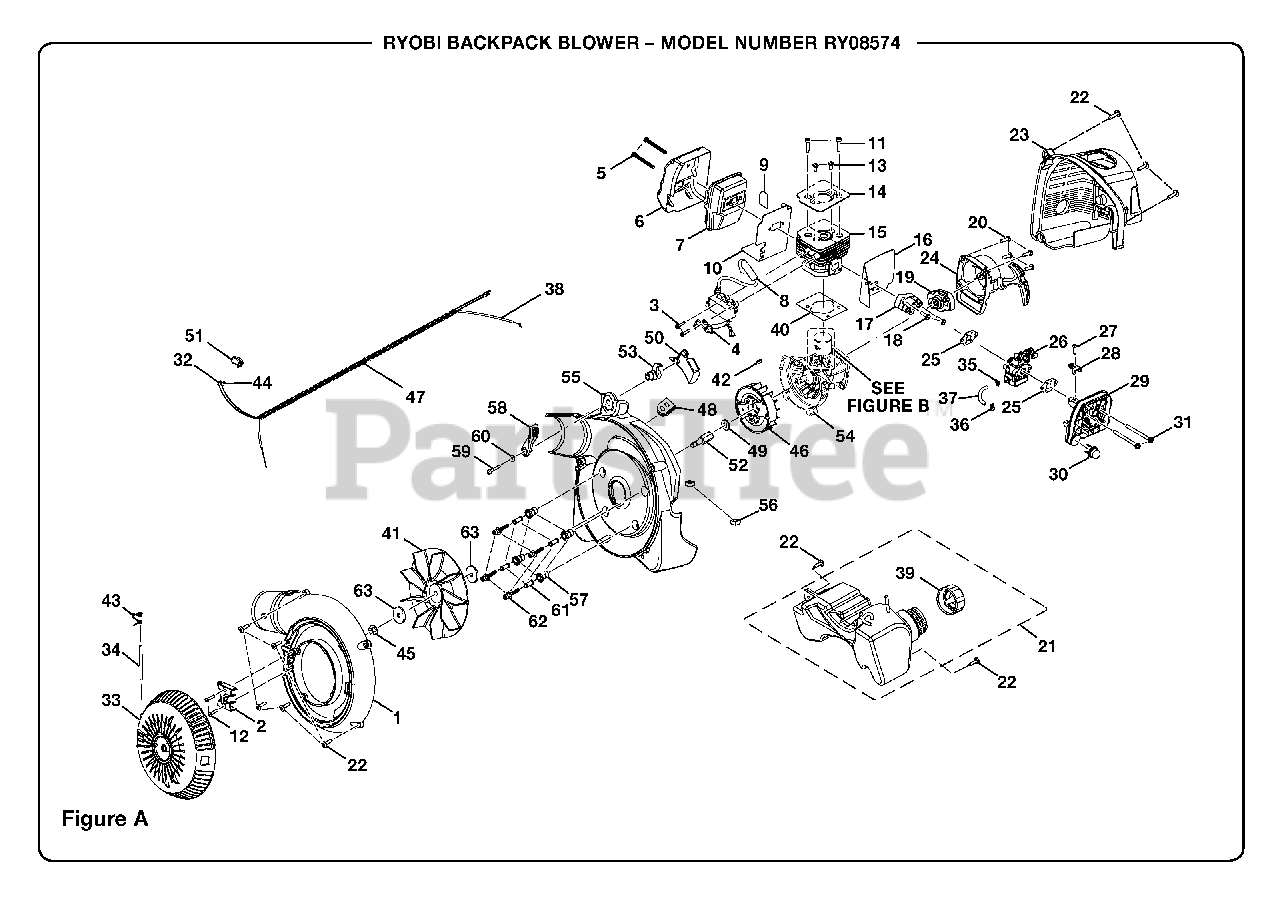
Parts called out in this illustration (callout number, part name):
1	Outer Volute Housing
2	Vacuum Door Hinge
3	Screw (M4 X 22 mm)
4	Lead Assembly
5	Screw (M5 X 50 mm)
6	Heat Shield
7	Muffler Assembly
8	Coil & Boot Assembly
9	Heat Shield
10	Gasket Muffler
11	Screw (M5 X 22 mm)
12	Screw (#8-14 X 163 mm)
13	Screw & Washer (M5 X 10 mm)
14	Plate for Cylinder
15	Cylinder
16	Insulator Gasket
17	Insulator
18	Screw & Washer (M5 X 31 mm)
19	Pulley Assembly
20	Screw (M5 X 16 mm)
21	Fuel Tank Assembly
22	Screw (#10-14 X 7/8 in)
23	Engine Shroud Housing
24	Starter Assembly
25	Carburetor Gasket
26	Carburetor
27	Screw (M4 X 175 X16 mm Pan Hd)
28	Clip-throttle Cable
29	Air Box Base
30	Primer Assembly
31	Screw (M5 X 60 mm)
32	Lead Assembly (Red)
33	Vacuum Door
34	Hinge Pin
35	Clip-hose (Id 4.9)
36	Clip-hose
37	Tubing Rubber
38	Cable Assembly
39	Fuel Cap Assembly
40	Cylinder Gasket
41	24.5 Cc Blower Fan
42	Key Woodruff (S43C)
43	Vacuum Door Hinge Spring
44	Lead Assembly (Black)
45	Retaining Washer Nut
46	Fly-wheel Assembly
47	Corrugated Tube
48	Rubber Grommet
49	Washer (2 mm)
52	Crank Shaft Extension
53	Trigger Lock
54	Crankcase Assembly
55	Housing Inner Volute
56	Square Nut
57	Vibration Isolator
58	Cruise Lever
59	Screw (#8-14 X 25 mm)
61	Bushing Sleeve
62	Screw (M5 X 8 mm Cap Hd)
63	Washer-fan Spacer
